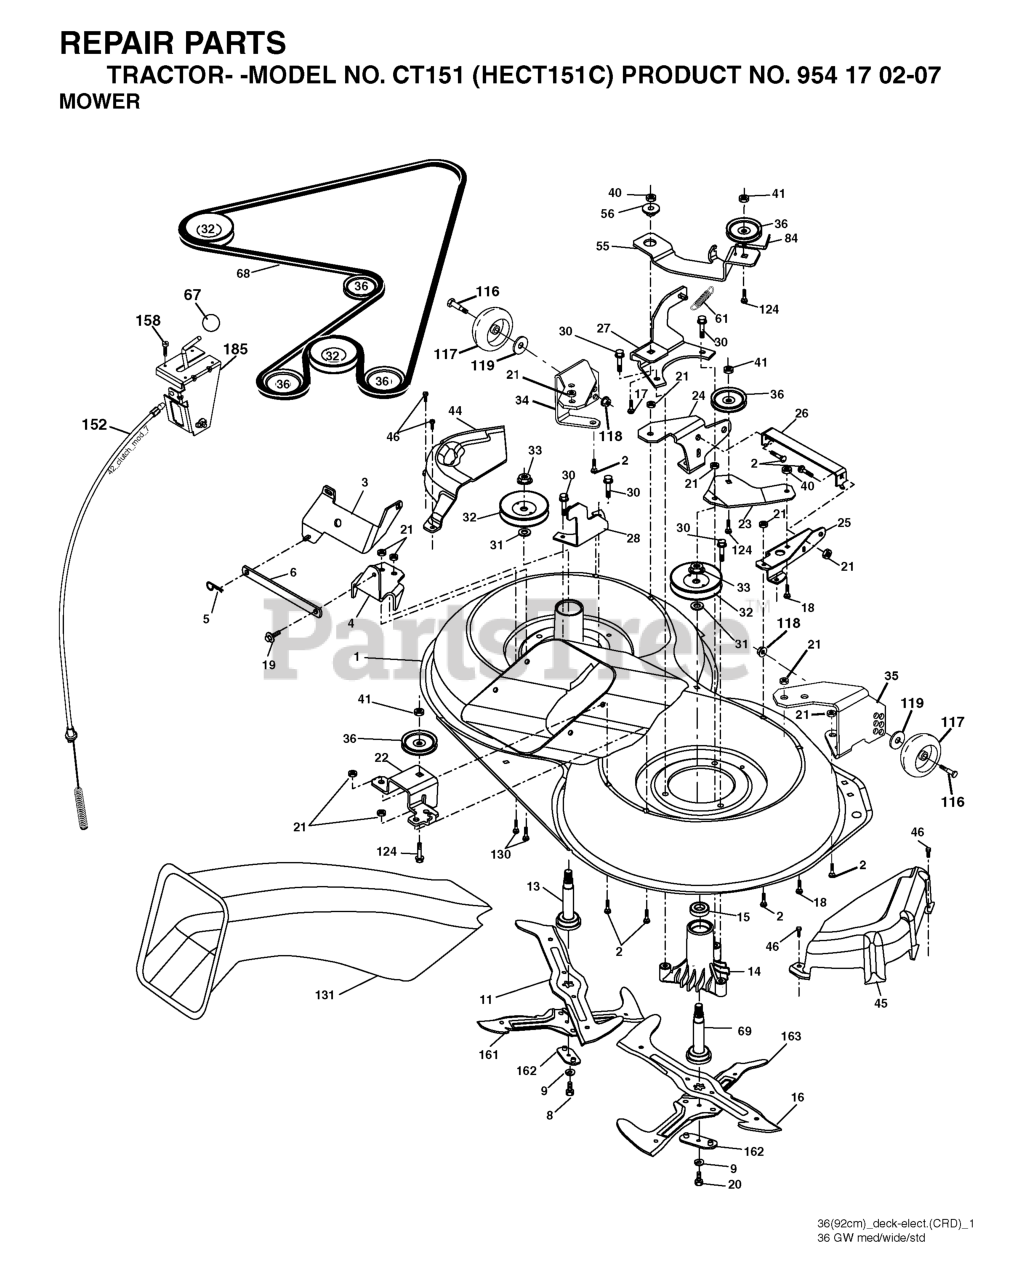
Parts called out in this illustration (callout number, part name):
1	MOWER HOUSING, DECK
2	RP BOLT 5/16-18 X3/4 ZN/YEL GR
5	RETAINER-SPRNG RB
6	BAR.SWAY.92.CRD
8	BOLT.3/8-24X1.25 GR8
9	LOCKWASHER
13	SHAFT ASM VENT
14	HOUSING.MANDREL.VENTED (MACHD)
17	BOLT.3/8-14X1.25
19	BOLT SHD 5/16-18
20	BOLT.3/8-24X1.25GR8. LHTHRD
21	LOCKNUT
26	BRACE.SUPT.SUSP.FRT.CRD
30	SCREW, WASHER HEAD
31	WASHER.SPACER.MANDREL
32	PULLEY, MANDREL
33	NUT, FLG TOPLOCK 9/16"
36	PULLEY.IDLER.4.25
41	NUT LOCK FLG 3/8-16 UNC
45	COVER.MANDREL.RH.CRD
46	SCREW.1/4-20X5/8
56	SPACER.RETAINER.MOWER
61	SPRING.TENSION.BELT
67	KNOB T (3/8 HOLE)
68	HEX-BELT
69	SHAFT.ASM.W/LWR.BRG.RH.THREAD
84	KEEPER, BELT IDLER
116	SHOULDER BOLT
117	WHEEL GAGE DONUT
118	LOCKNUT
119	WASHER.5/16.FLAT.STE.STD.
124	BOLT.3/8-16X1.50
130	BOLT.CARR.SQNK.5/16-18UNC.X3/4
131	CHUTE BAGGER
158	SCREW
185	HEAD ASM. CABLE CLUTCH
